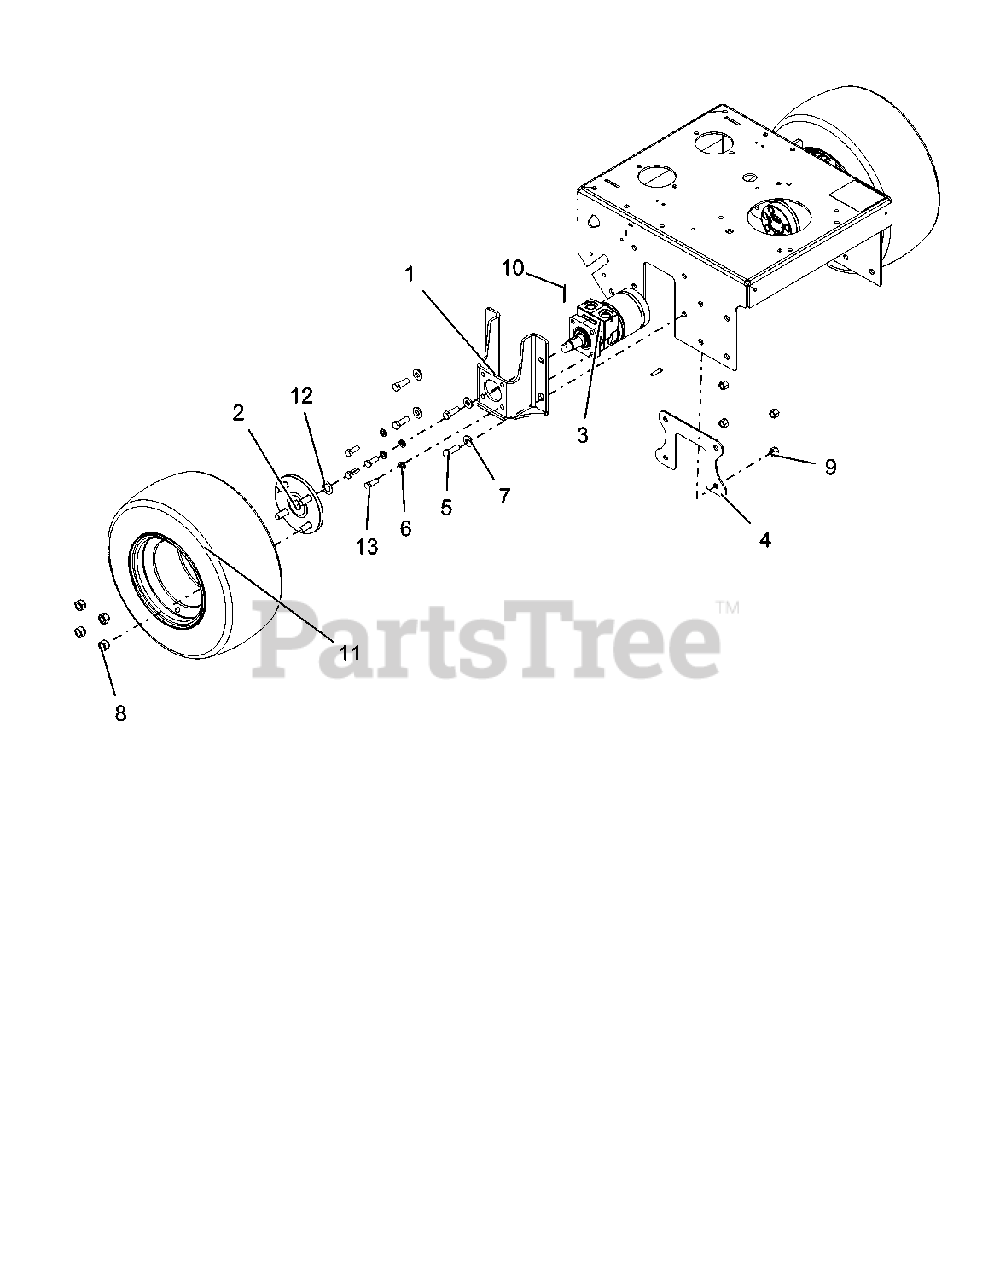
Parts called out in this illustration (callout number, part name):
1	WLDMT, WHEEL MOTOR BRACKET-RED
2	ASSY, WHEEL HUB
3	MOTOR, HYDRAULIC WHEEL
4	PLATE, ENGINE BED DOUBLE-RED
5	BLT-HEX .44-14X1.25 GR5 YWZC
6	WSHR-LK .38X.094 REG YWZC
7	WSHR-FL-STL .468X1.00X.125 YWZC
8	NUT, LUG .500-13
9	NUT-LK-NYL .44-14 YWZC
10	@PIN-CTR .12X1.50 EXTPRSQCT YW
11	ASSM, WHL/TIRE 16X6.50-8 K500
12	BUSHING, MACH .75 X 1.25 X .048
13	BOLT, 3/8-16 X 1 GR8 BLACK
